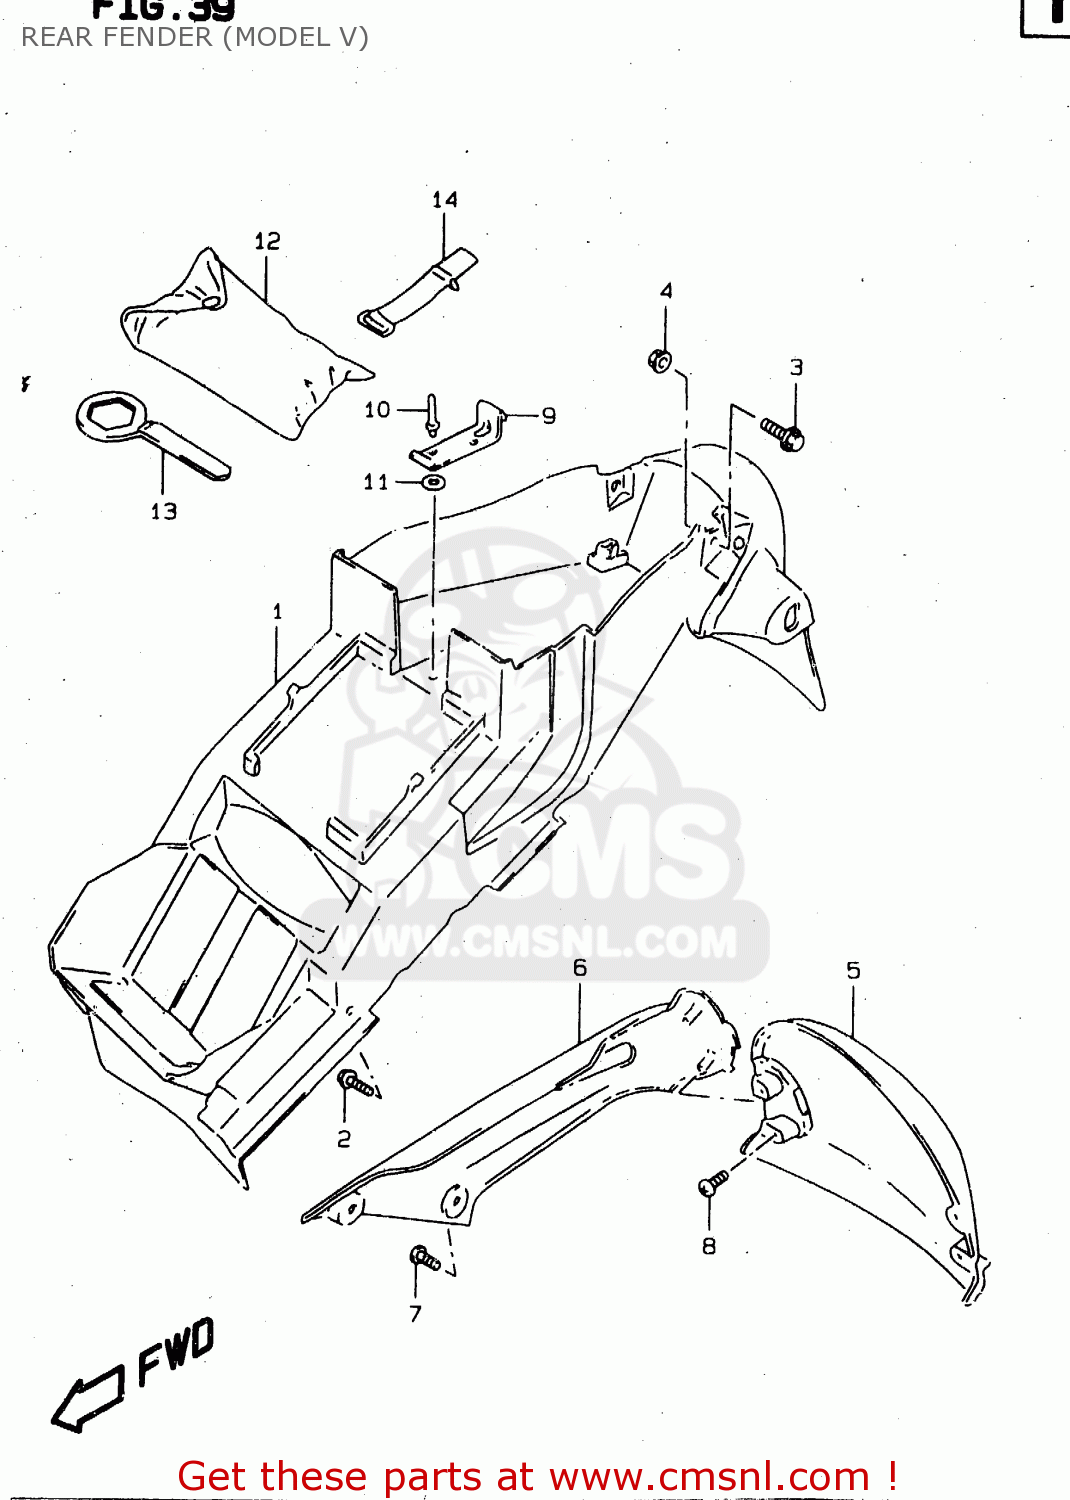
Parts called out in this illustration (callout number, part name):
1	FENDER,RR
2	BOLT 6X16.5
3	BOLT 6X16
4	NUT
5	FENDER,RR LOW CTR
6	FENDER,RR LOW,R
7	SCREW
8	SCREW
9	HOLDER,TOOL
10	RIVET
11	WASHER
12	TOOL ASSY
13	RING SPANNER(36)
14	BAND,TOOL
